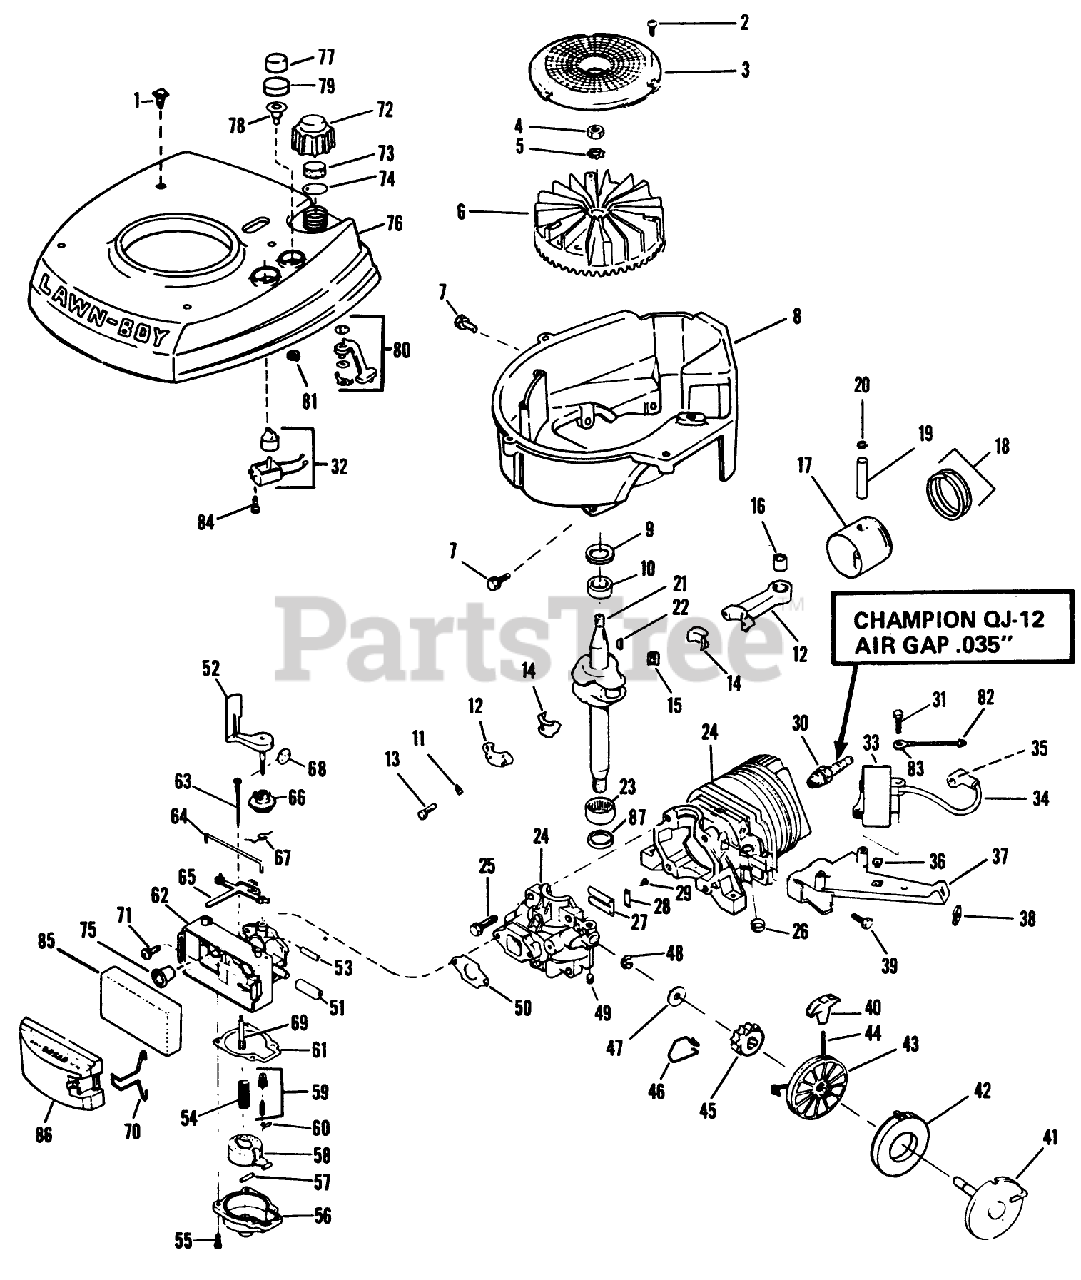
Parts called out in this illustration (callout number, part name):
1	SCREW S
2	SCREW F
7	SCREW-SEMS
8	SHRD BASE & EYELET
10	BEARING V
13	SCREW
13	SCREW-HSH
14	LINER ASM
16	BEARING AY F
20	RING-RETAINING
22	KEY
23	BEARING V
25	SCREW S
26	PLUG-CORE VF
28	PLATE-BACKUP, REED
32	SWITCH
34	HT LEAD&COVER XEV
36	NUT-CLIP
38	NUT - SPEED S
40	HANDLE STARTER S
42	SPRING S
43	PULLEY STARTER S
46	SPRING F
47	WASHER S
50	GASKET CARB S
51	GAS LINE
52	AIR VANE&SHAFT S
53	TUBING PRIMER S
54	FILTER-FUEL VS
55	SCREW-HH
62	CARB BODY S
63	NEEDLE ADJ. AY S
64	RETAINER
65	LEVER S
66	COLLAR-ADJUST, AIRVANE
67	SPRING,THROTTLE S
68	DISC S
70	RETAINER-COVER, FILTER
71	SCREW
73	BAFFLE - FOAM SM
74	GASKET S
79	FILTER S
81	LOCKNUT S
83	TERMINAL S
87	SEAL-OIL
